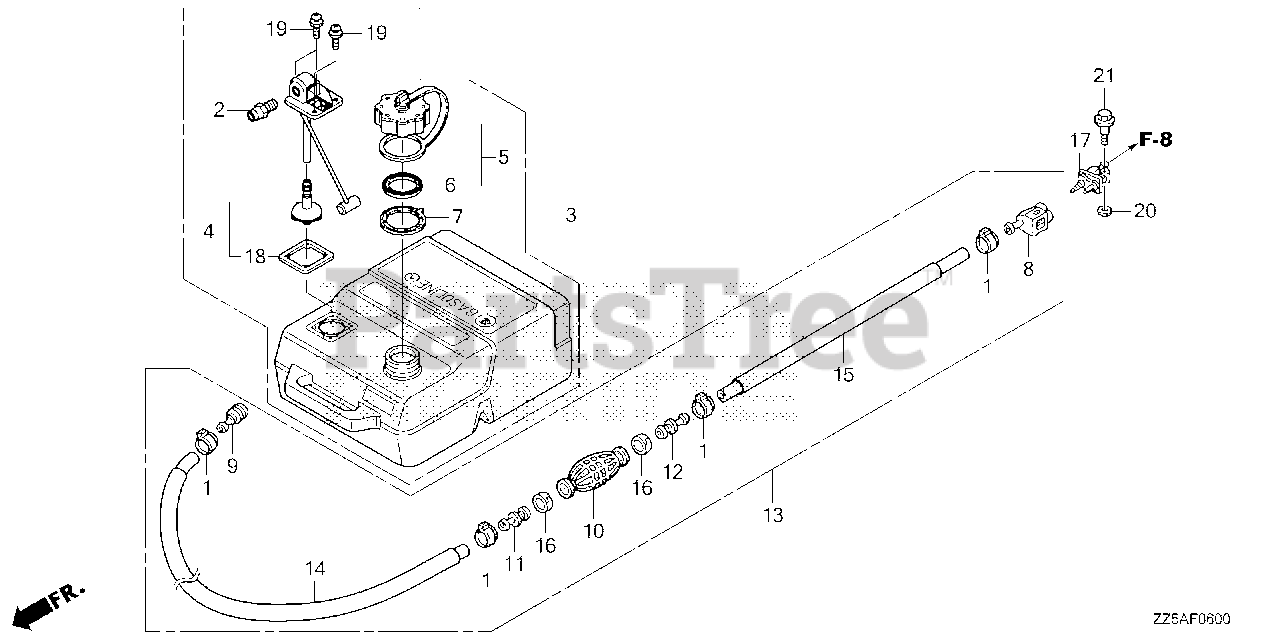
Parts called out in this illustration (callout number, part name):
1	CLAMP, FUEL TUBE (14.0)
2	FITTING, QUICK DISCONNECT
3	TANK ASSY., FUEL
4	FILTER KIT, FUEL
5	CAP, FUEL FILLER
6	GASKET, FUEL CAP
7	RETAINER, PRESSURE RELIEF
8	CONNECTOR ASSY., FUEL (A)
9	CONNECTOR, FUEL
10	BULB, PRIMER
11	VALVE, IN.
12	VALVE, OUTLET
13	TUBE ASSY., FUEL TANK
14	TUBE, FUEL LONG (7.3X2000)
15	TUBE, FUEL SHORT
16	BAND, TUBE CLIP (20MM)
17	CONNECTOR ASSY., FUEL (B)
18	GASKET, FUEL PICK-UP
19	BOLT-WASHER (5MM) (SEAL)
20	WASHER, PIVOT
21	BOLT, SPECIAL (6X22) (CT200)
